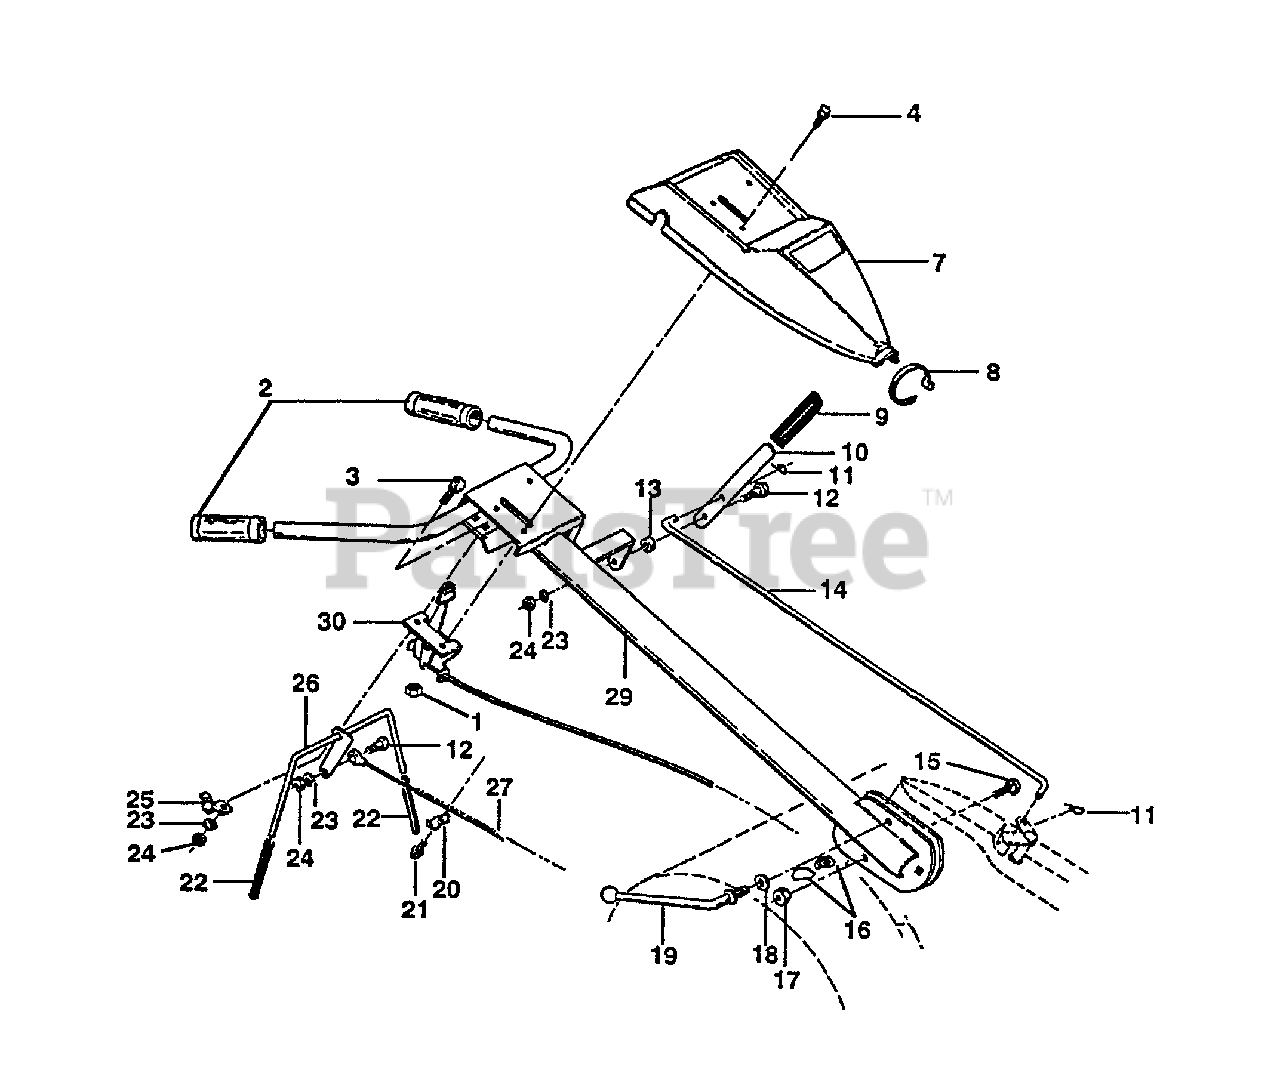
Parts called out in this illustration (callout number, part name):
1	Nut, Keps #10-24 UNC
2	Grip, Handle
3	Bolt, Carriage 1/4-20
4	Screw, Truss Hd. #10-24 UNC x 1/2
7	Panel, Control
8	Tie, Cable
9	Grip, Handle
10	Handle, Shift
11	Clip, Hairpin
12	Bolt, Shoulder
13	Grommet, Rubber
14	Rod, Shift
15	Bolt, Carriage 3/8-16 x 1 Gr. 5
16	Lock, Handle
17	Nut 3/8-16
18	Washer 13/32 x 1 x 11 Ga.
19	Lever, Lock, Handle
21	Screw, Hex Washer Hd. Slotted #10-24 x 1/2
22	Grip, Bar, Control
23	Washer, Lock 1/4
24	Nut, Hex 1/4-20
25	Clamp, Bar, Control
26	Bar Assembly, Control
27	Cable, Clutch
29	Handle
30	Control, Throttle
